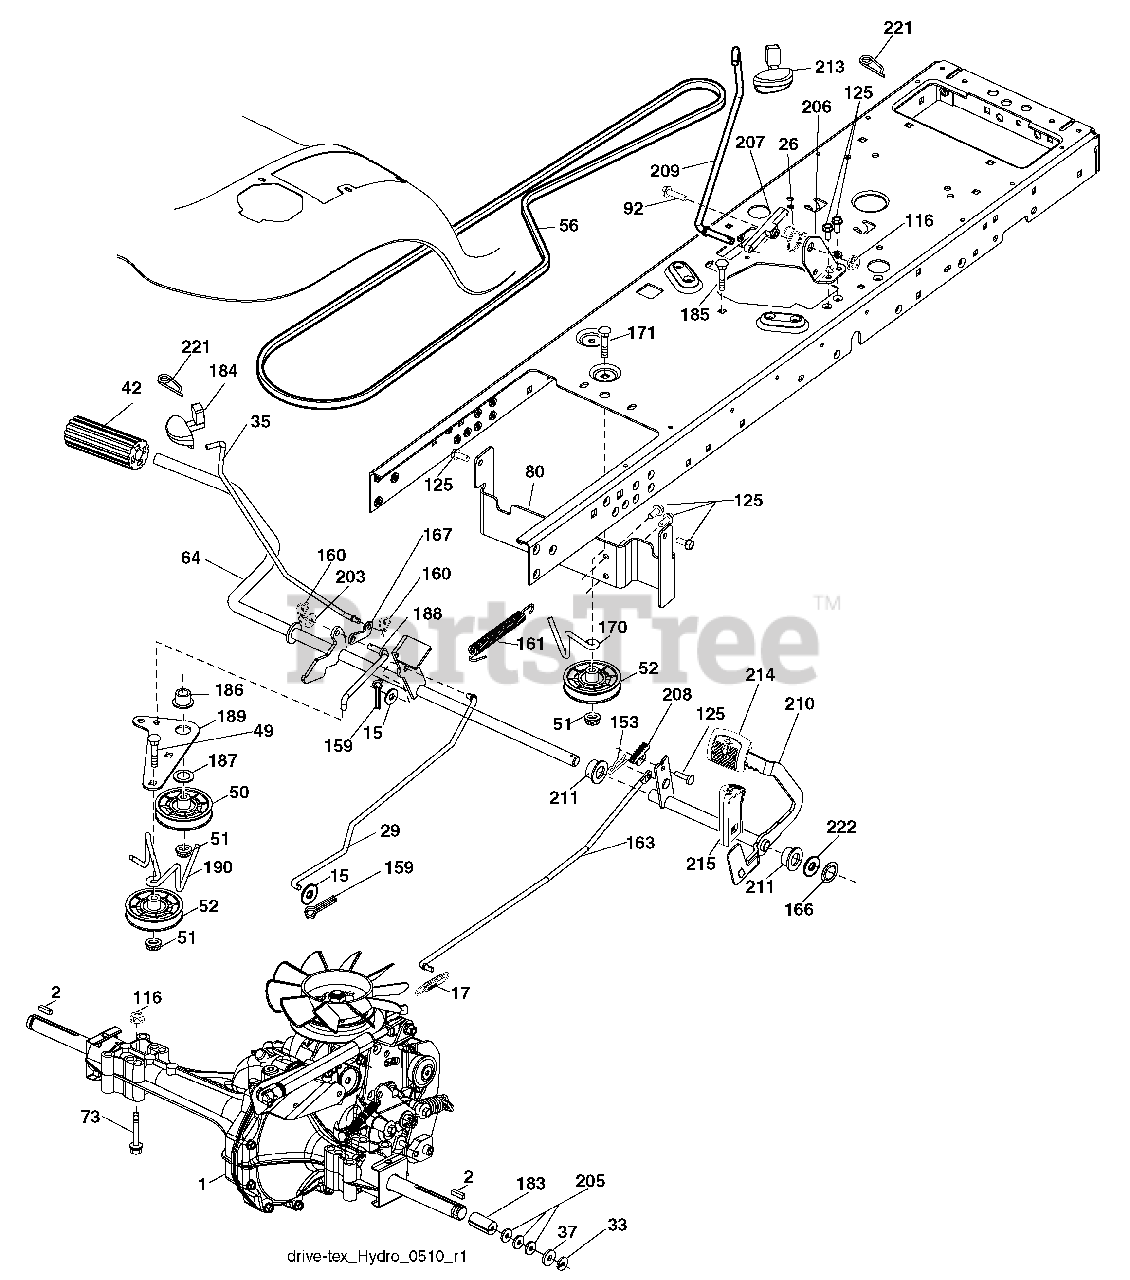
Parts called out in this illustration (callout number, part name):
2	Key
15	Washer 13/32 x 13/16 x 16 Ga.
17	Spring, Brake
26	Spring Return Cruise
29	Rod, Brake
33	Ring E
35	Rod, Brake, Park
37	Washer 25/32 x 1-1/4 x 16 Ga.
42	Cover, Foot Pedal
49	Bolt
50	Pulley Idler Flat
51	Lock Nut 3/8-16
52	Idler V-Groove 910" Offset
56	V-Belt, Drive
64	Shaft Asm. Pedal Brake Control
73	Bolt 5/16-18 Gr. 5
80	Bracket Strap Torque
92	Bolt Fin Hex 5/16-18 unc x 1.25
116	Nut Lock Hex Flange 5/16-18
125	Screw 5/16-18 x 3/4
153	Retainer Spring
159	Pin Cotter 1/8 x 3/4
160	Retainer Clip
161	Spring, Return, Clutch
163	Rod Pedal Control
166	Nut Push .625
167	Latch Brake Parking
170	Keeper Belt Centerspan
171	Bolt
183	Spacer Axle
184	Handle Parking Brake
185	Bolt
186	Spacer Retainer
187	Washer
188	Link Clutch Ground Drive
189	Bellcrank Ground Drive
190	Keeper Bellcrank Ground Drive
203	Washer 11/32 x 11/16 x 16 Ga.
205	Washer 25/32 x 1-5/8 x 16 Ga.
206	Bracket Mount Latch Cruise
207	Latch Control Cruise
208	Gear Sector Control Cruise
209	Rod Control Cruise
210	Rockr Asm. Pedal Control
211	Bearing Nylon
213	Knob control Cruise
214	Pad Pedal Forward
215	Pad Pedal Reverse
221	Retainer Spring Clip Handle
222	Washer 21/32 x 1-1/4 10 Ga.
